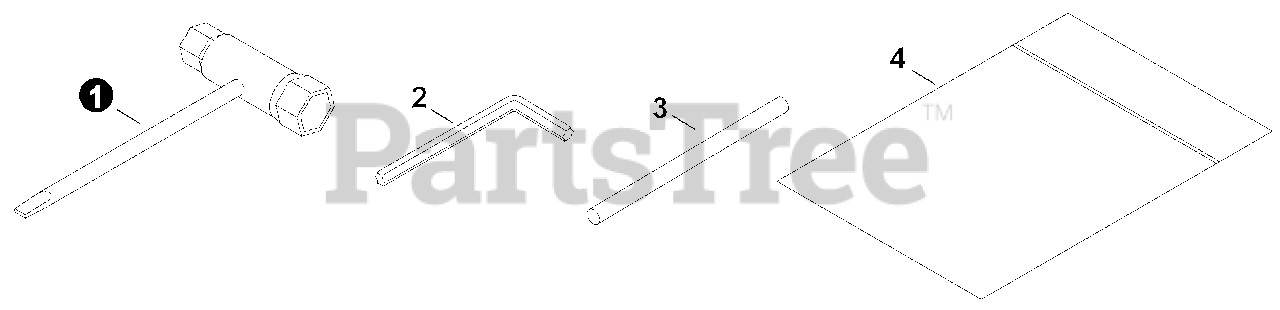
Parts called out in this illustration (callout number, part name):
1	T-WRENCH 17x19 L200
2	WRENCH, ALLEN
3	TOOL, LOCKING 5x120 MM
4	BAG, TOOL
